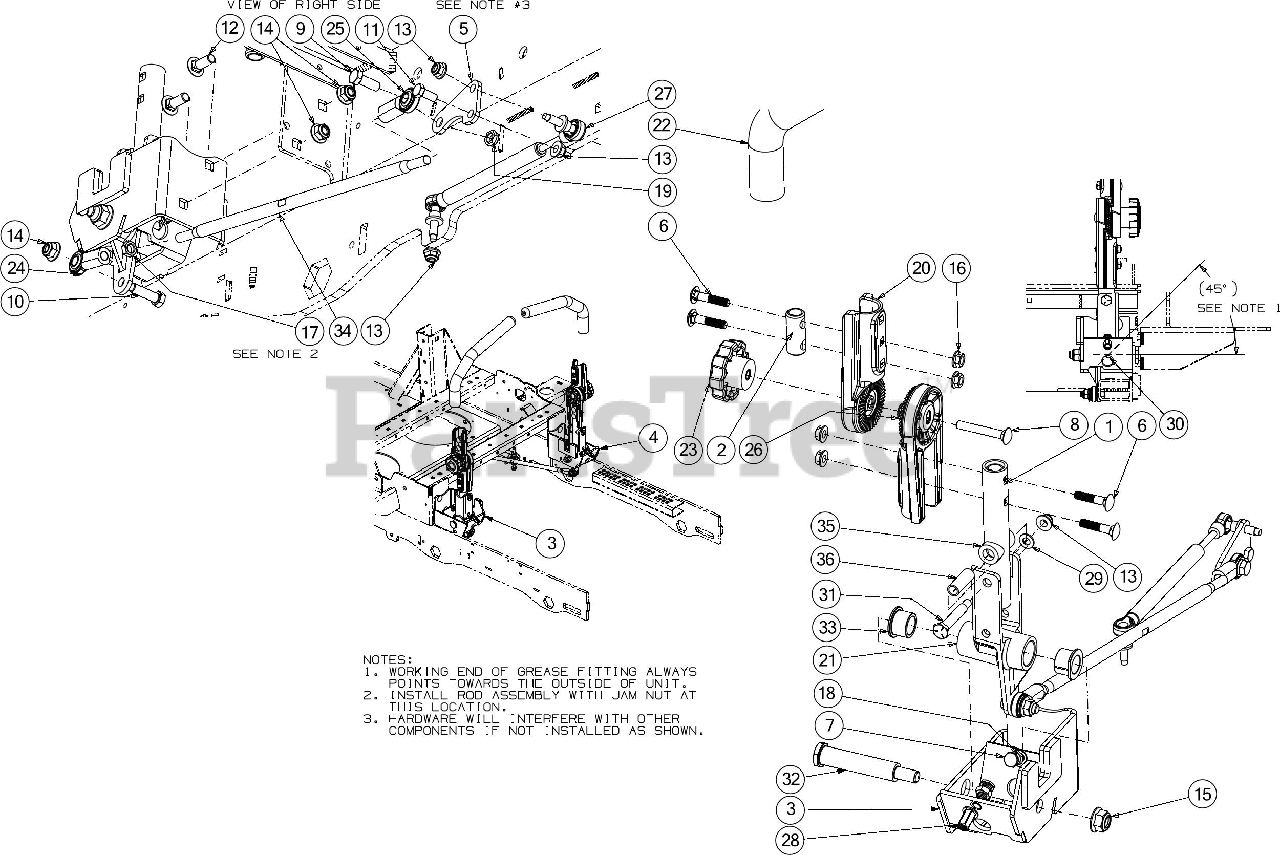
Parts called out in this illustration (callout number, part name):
1	LOWER PIVOT TUBE BRACKET
2	LAPBAR BRACKET
3	PIVOT LAPBAR HOUSING (RH)
4	PIVOT LAPBAR HOUSING (LH)
5	RETURN BRACKET
6	CARRIAGE BOLT 5/16-18 x 1.50
7	SCREW 3/8-16X1.0 GR5 SPEC
8	SCRE W5/16-18 x 2.25 GR5
9	SCREW 3/8-16 x 1 GR5
10	SCREW 3/8-16 x 1.25 GR5
11	SCREW 5/16-18 x .75 GR5
12	CARRIAGE BOLT 3/8-16 x 1.00 GR5
13	FLANGE LOCK NUT 5/16-18
16	FLANGE NUT
17	HEX JAM NUT 3/8X24
19	TOP LOCK NUT
20	HANDLE ADJUST
23	KNOB-5/16-18
24	BALL JOINT (RH)
25	FEMALE BALL JOINT (LH)
27	DAMPER CYLINDER
28	NUT RIVET
29	FLAT WASHER
30	45 DEGREE LUBE FITTING 1/4-28 TAPER
31	SHOULDER SCREW
32	SHOULDER BOLT .750 DIA x 3.25 LG
33	FLANGE BEARING
34	CONTROL ROD
35	NYLON SPACER
